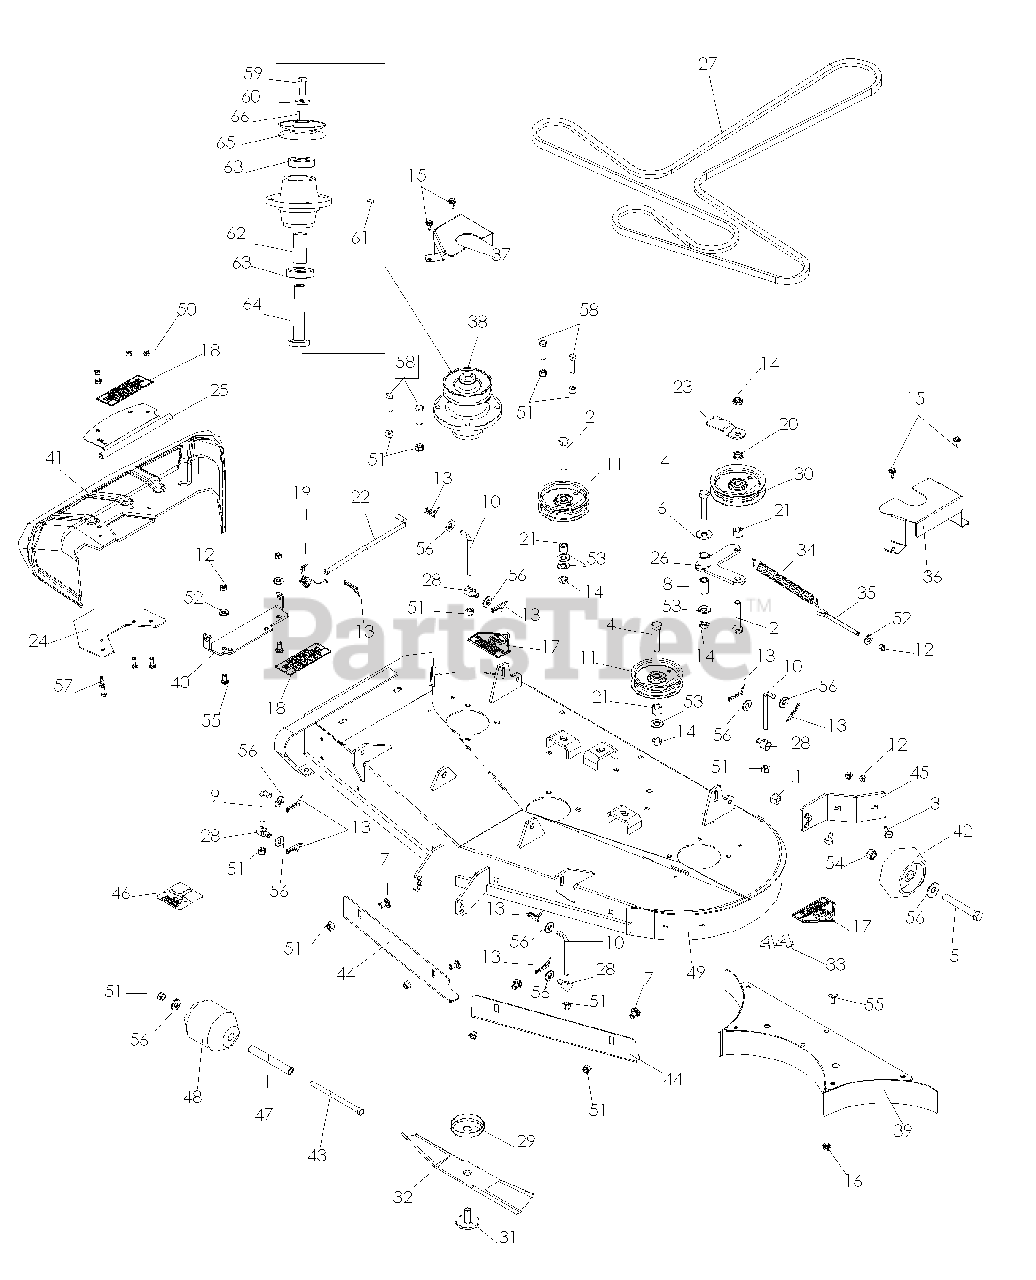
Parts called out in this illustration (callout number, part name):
1	NUT 1/2-13 HEX NYLOC ZD
2	HCS 1/2C X 2 3/4
3	RHSSNB 5/16C X 1.0
4	HEX SCREW 1/2-13 X 2.5" GR 5
5	HCS 1/2-13 X 4 GR 5 ZD
6	WASH USS FLAT 1/2
7	RHSNB 3/8-16 X 3/4 GR5 ZD
8	BUSHING DIXON 1080
9	L ROD 3-1/8"
10	L ROD 3-7/8
11	PULLEY IDLER
12	NUT 5/16 NYLOC
13	PIN, COTTER 1 3/4
14	NUT, 1/2-13 THIN PROF NYL
15	SCREW, TAP & DR #12-14 X 3/4
16	5/16-18 FLANGED L-NUT
17	DECAL, CPSC
18	DECAL, DANGER
19	SPRING, TORSION
20	HD PULLEY SPACER
21	BUSHING
22	DEFLECTOR PIN
23	BELT GUARD BLK
24	DEFLECTOR BRKT
25	DEF. BRKT. ASM.
26	IDLER WLDT.
29	TRASH GUARD
30	IDLER PULLEY
31	BLADE BOLT
32	BLD 44" HI LIFT FUS
33	DECAL, DECK 44"
34	SPRING, DECK BELT
35	EYE BOLT 4.5`
36	PULLEY GUARD
37	PULLEY GUARD
38	HUB ASM
39	44 W-BAFFLE WLDT.
41	44 DEFLECTOR
42	GAUGE WHEEL
43	BOLT 3/8 X 6 GR5
44	BLOW-BY BAFFLE
45	ROLLER BRKT.
46	DECAL, BELT ROUTING (18656)
47	BUSHING
48	ROLLER 3-3/4 DIA. X 4-1
49	DECK W/W-BAFFLE 44" DIX
50	NUT 1/4-20 NYLOC
51	NUT 3/8-16 NYLOC
52	FLAT WASHER 5/16 SAE
53	WASHER 1/2" FLAT
54	NUT HEX 1/2
55	BOLT 5/16C X 3/4" CARRIAGE
56	WASHER 3/8 FLAT
57	HCS 1/4C X 3/4 HCS
58	HCS 3/8C X 1 1/2
59	1/2-20 UNF X 1 1/4 HHBLT
60	WASHER .525 X 1.375 X .25
61	ZERK, 3/16, DRIVE IN
62	HUB SPACER-2.349
63	BEARING - 6305 - 2RS
64	SHAFT 50S
65	V-PULLEY
66	OUTER SHAFT KEY
